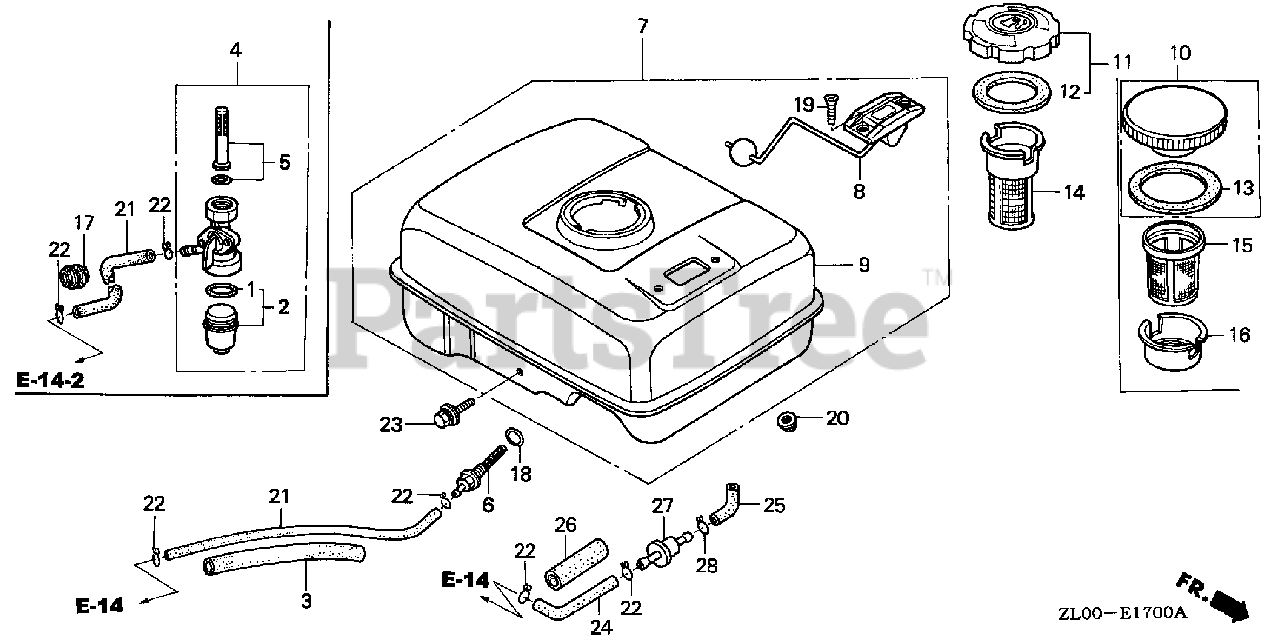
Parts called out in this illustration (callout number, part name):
3	RUBBER, SUPPORTER (107MM)
21	BULK HOSE, FUEL (4.5X3000) (4.5X140)
22	CLIP, TUBE (B8)
